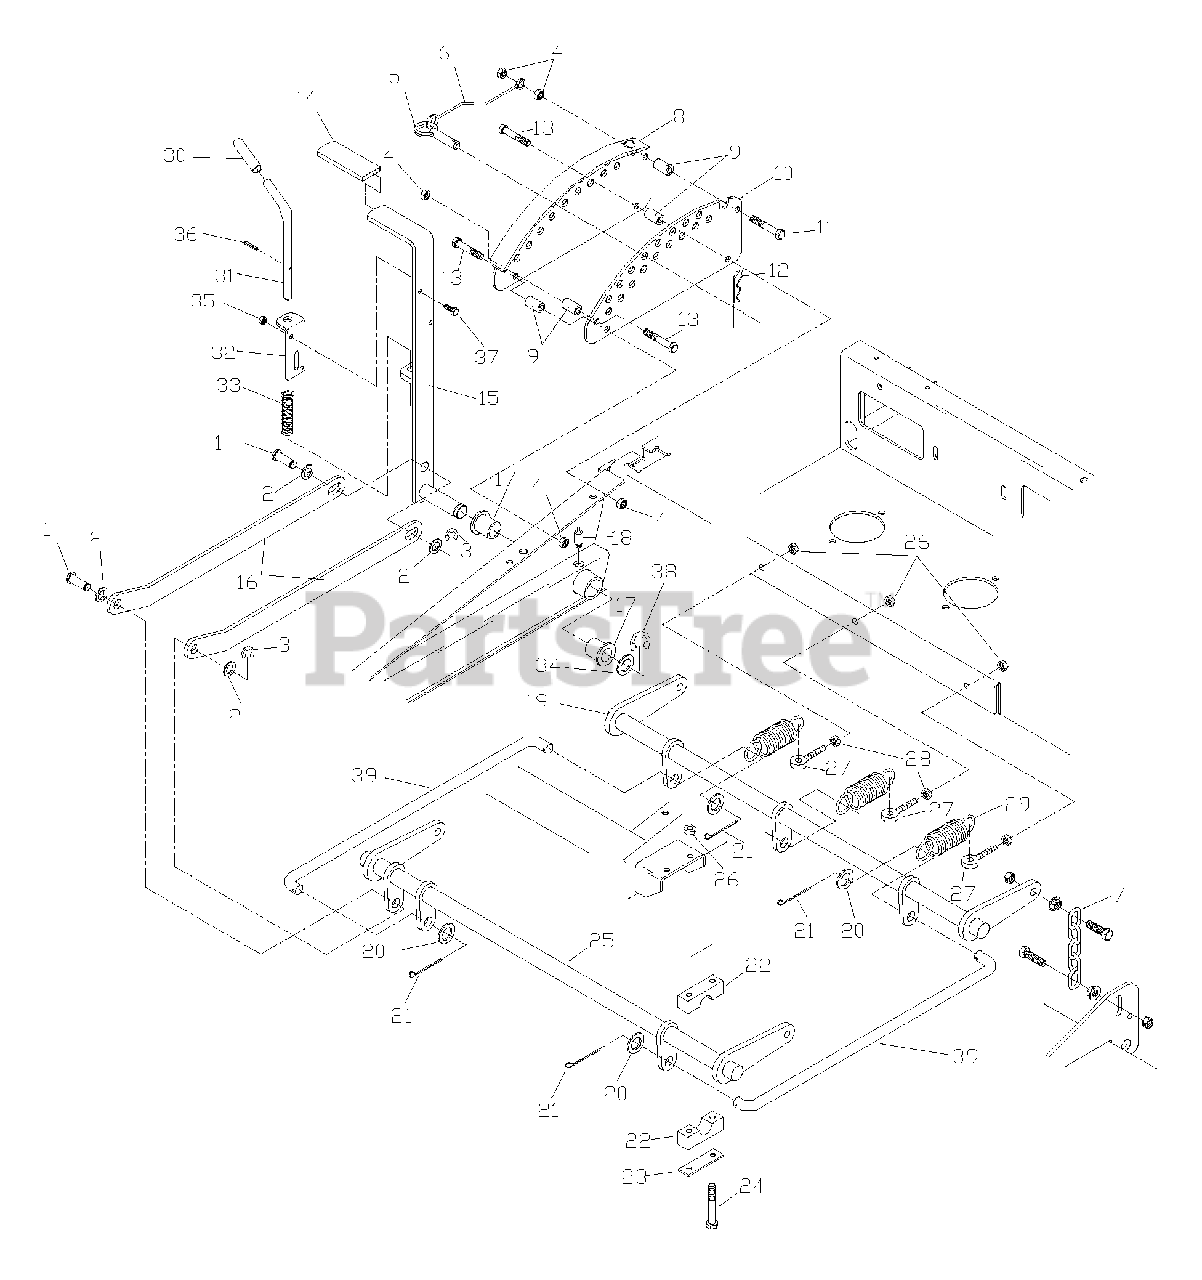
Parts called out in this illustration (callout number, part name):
1	CLEVIS PIN
2	MACH. BUSHING
3	5/8 E - RING
4	NUT 3/8C CTR. LOCK
7	LIFT CHAIN
8	ADJ. PLATE WLDMT.
9	DECK LIFT SPACER
10	ADJ. PLATE PAINTED
11	HCS 3/8C X 2.5
12	# 4 HAIR PIN
13	HCS 3/8C X 2.25
15	LEVER WLDMT.
16	LIFT LINKAGE
17	FLANGE BUSHING
18	ZERK - LONG
19	LIFT SHAFT
20	5/8 SAE WASHER
21	COTTER PIN
22	PILLOW BLOCK
23	SUPPORT PLATE
24	HCS 5/16C X 2.5
25	LIFT SHAFT, FRONT
26	NUT 5/16C CTR. LOCK
28	5/16C WHIZ NUT
29	DECK LIFT SPRING
32	PIN MT.,UPPER
34	MACH. BUSHING
35	NUT 1/4C CTR. LOCK
36	3/16 X 1 ROLL PIN
37	HCS 1/4C X 3/4
38	7/8 E - RING
39	CONN. LINK
